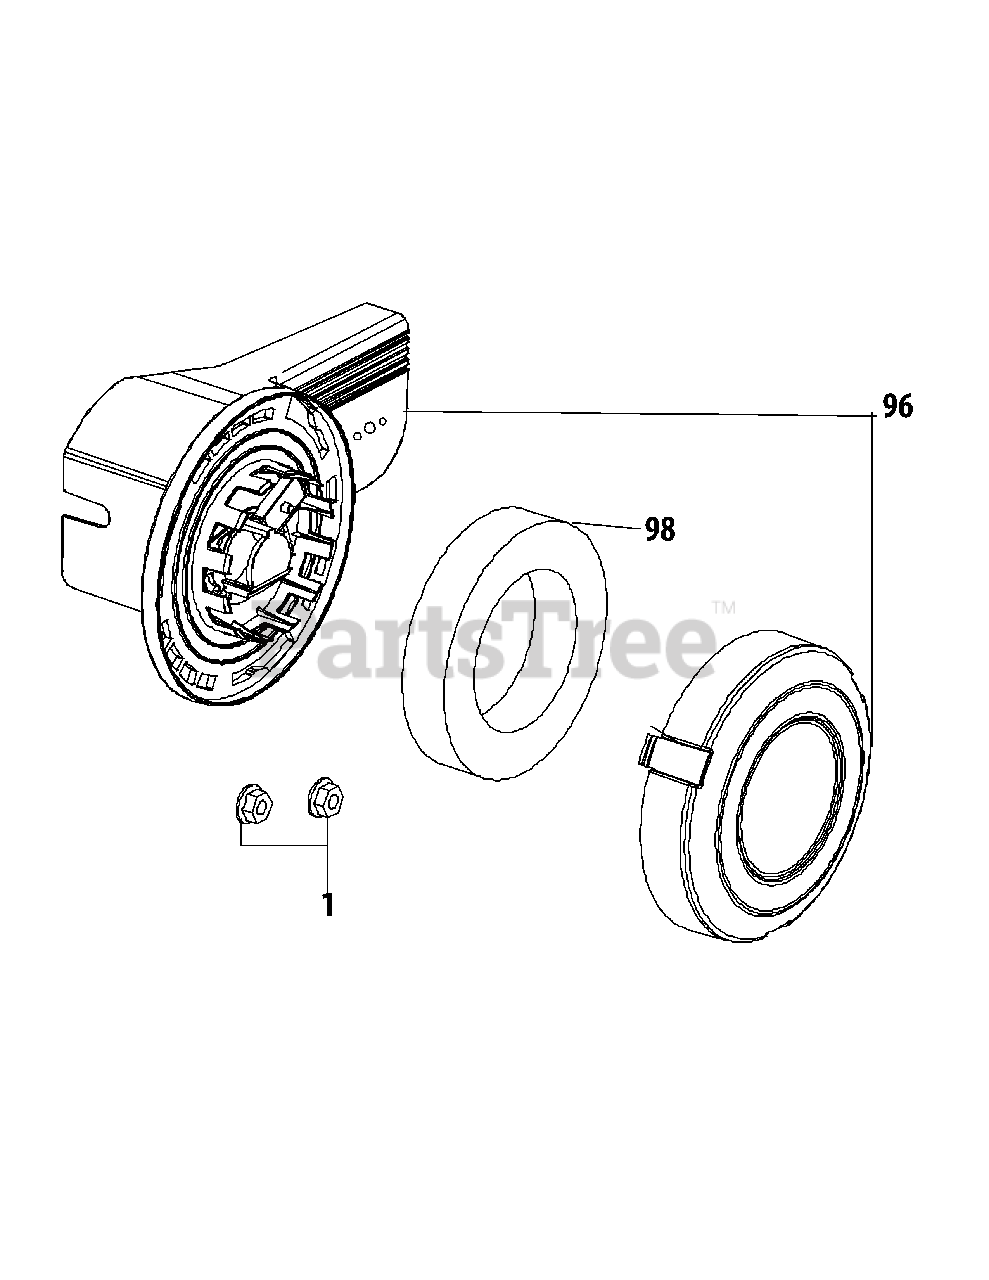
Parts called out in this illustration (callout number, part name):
1	Nut M6X10Mm Starter/Carb/Muff
96	Air Filter Assembly
98	Air Filter Element, Paper
